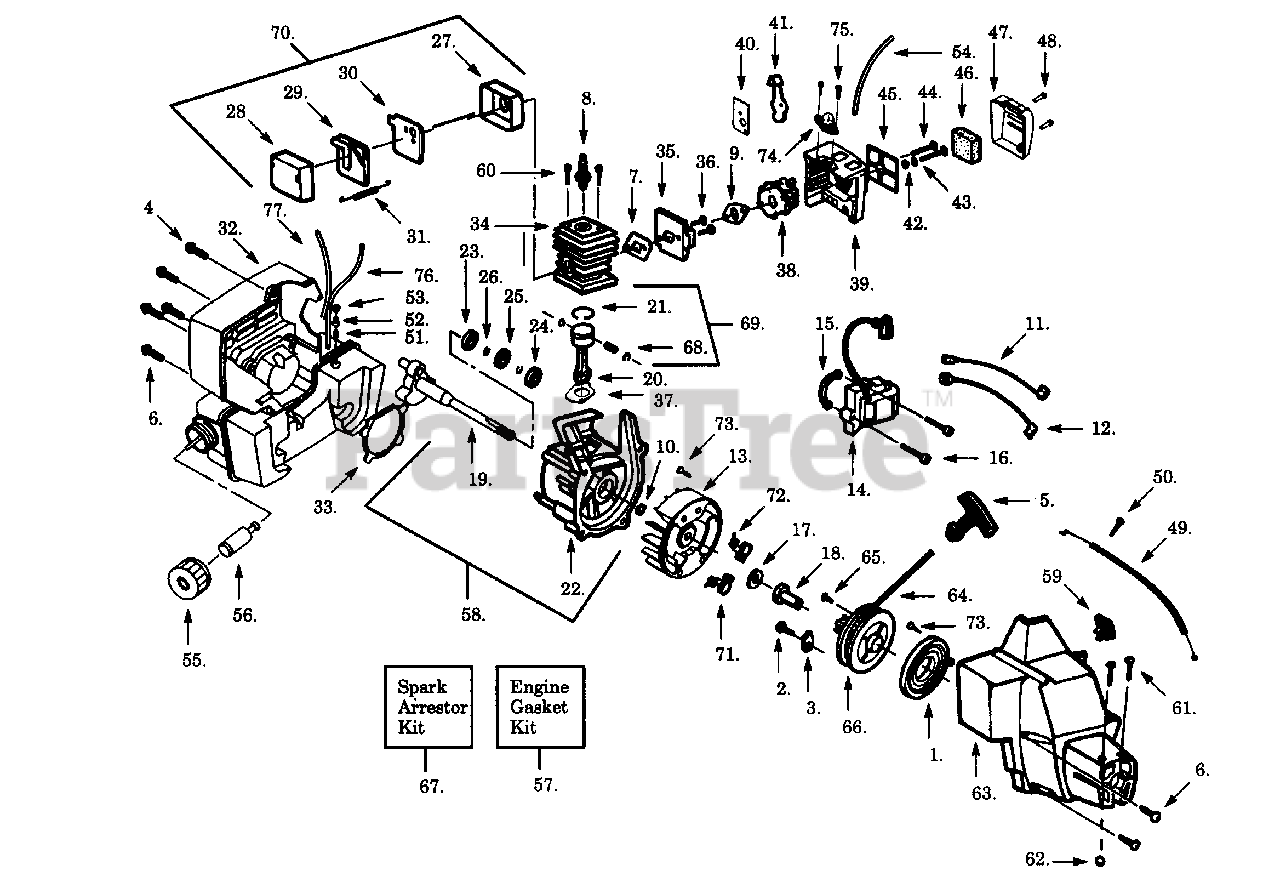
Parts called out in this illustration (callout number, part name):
1	Starter Spring
3	Retainer
5	Starter Handle
6	Screw
7	Cylinder Gasket
8	Spark Plug
10	Retainer
11	Lead Wire
12	Ground Wire
13	Flywheel Ass'y.
14	Ignition Module
18	Drive Coupling
19	Crankshaft Ass'y.
20	Connecting Rod Ass'y.
21	Piston Ring
22	Crankcase Ass'y.
23	Inner Bearing
24	Outer Bearing
25	C'case Seal
26	Retaining Ring
27	Muffler Body
28	Muffler Cover
29	Muffler Baffle-Exit
30	Muffler Baffle-First
31	Muffler Spring
32	Shroud & Tank Assy., Type 1
32	Shroud & Tank Assy., Type 2 & 3
34	Cylinder
38	Carburetor, Type 1 (WA-215)
38	Carburetor, Type 2 & 3 (WA-218)
39	Air Box, Type 1
39	Air Box, Type 2 & 3
40	Choke Plate
41	Choke Shutter
42	Wave Washer
43	Choke Spacer
45	Filter Plate
46	Air Filter Foam
47	Air Filter Cover
49	Throttle Cable Ass'y.
51	Check Valve
53	Retainer
54	Fuel Line-Prim./Carb
55	Fuel Cap Ass'y.
56	Fuel Pickup Ass'y.
57	Engine Gasket Kit
58	C'case & C'shaft Assy.
59	On/Off Switch
63	Fan Housing
64	Rope Kit
66	Starter Pulley
67	Spark Arrestor Kit
68	Piston Pin Retainer
69	Piston Kit
70	Muffler Kit
71	Starter Dog
72	Starter Spring
73	Screw-Flywheel
74	Primer Bulb Ass'y. Type 2 & 3
75	Screw-Primer Type 2 & 3
76	Fuel Line-Prim./Tnk.
77	Fuel Line-Carb/Tnk.
